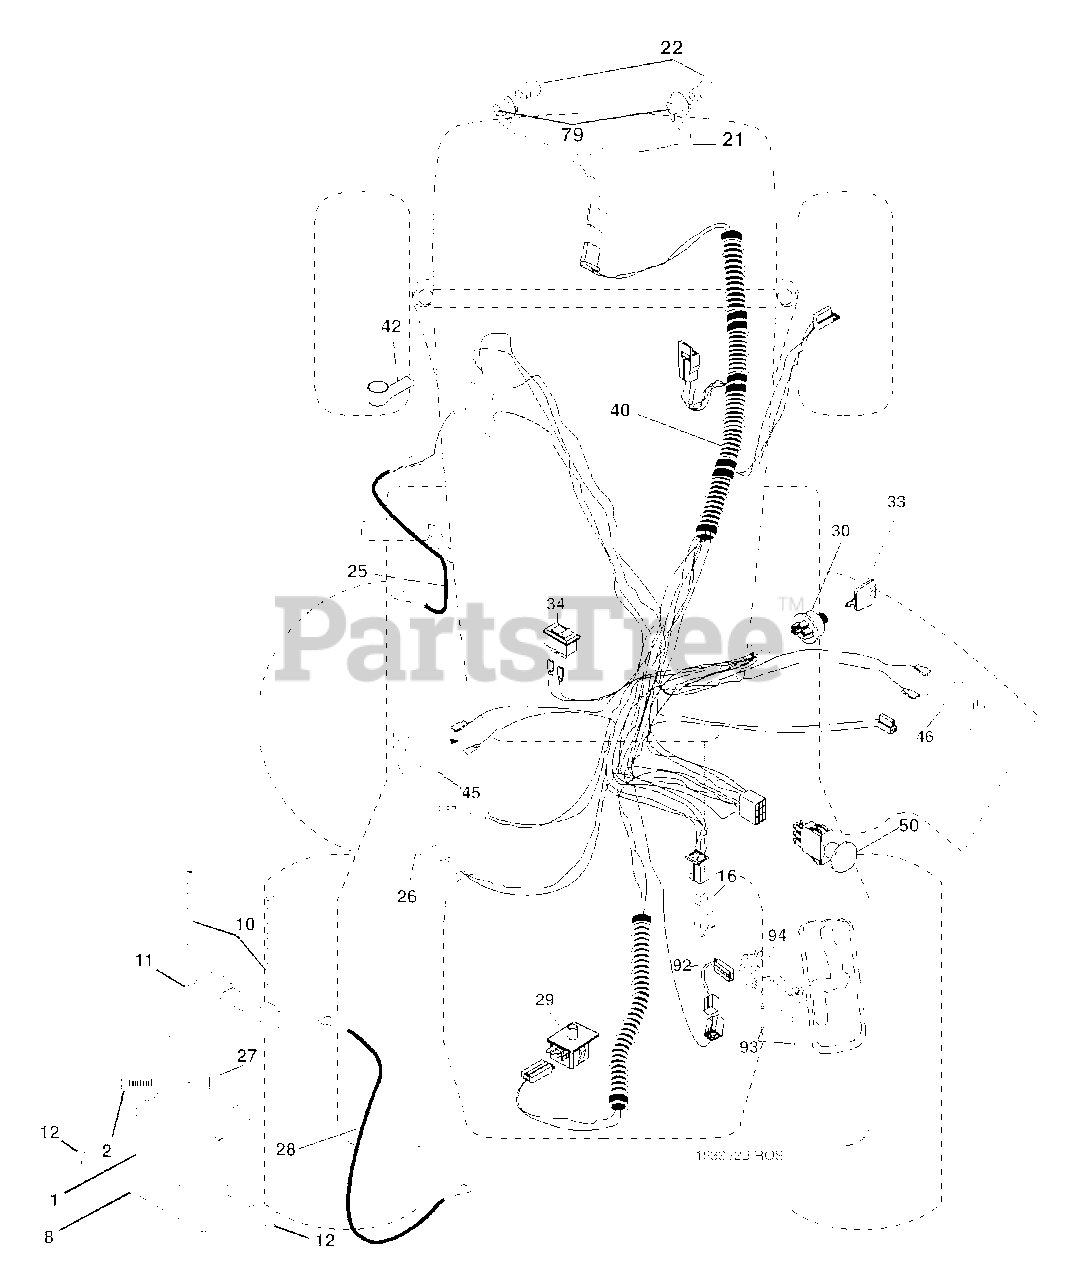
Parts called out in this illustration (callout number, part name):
1	Battery
2	Bolt Hex Head 1/4-20 x 3/4
8	Tray, Battery
10	Bolt, Battery Front 1/4-20 x 7.5 Zinc
11	Holddown Battery Front Mount
12	Nut, Push Nylon 1.4" Battery Front
16	Switch Interlock Push-In
21	Harness Socket Light w/41 52J
22	Bulb Light
27	Nut Keps Hex 1/4-20
28	Cable Bolt Ground
29	Switch, Seat
30	Switch, Ign
34	Switch Light/Reset B/B/Red
40	Harness Ign.
42	Cover, Terminal Red
50	Switch, PTO
79	Bulbholder Asm
92	Harness Pigtail Reverse Switch
93	Screw 10-14 x 2.0
94	Modual Reverse ROS
